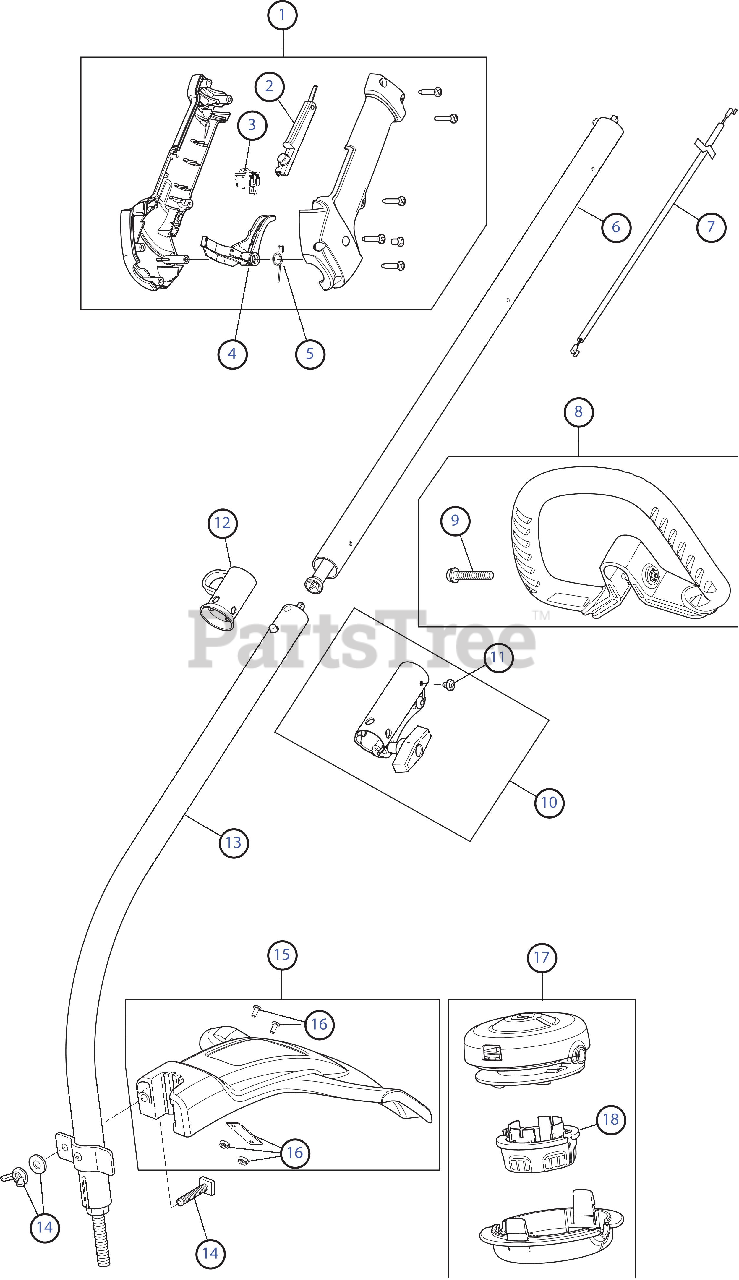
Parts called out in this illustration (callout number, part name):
1	Throttle Housing Assembly (Incl. 2 - 5)
2	Throttle Trigger Lock-Out
3	Throttle Switch Assembly
4	Throttle Trigger
5	Throttle Trigger Spring
6	Upper Drive Shaft Assembly
7	Throttle Cable Assembly
8	D-Handle Assembly (Incl. 9)
10	Split Boom Coupler (Incl. 11)
11	Coupler Anti-Rotation Screw
13	Lower Drive Shaft Housing
14	Shield Mount Hardware
15	Shield Assembly (Incl. 16)
16	Blade Assembly
17	Cutting Head Assembly (Incl. 18)
